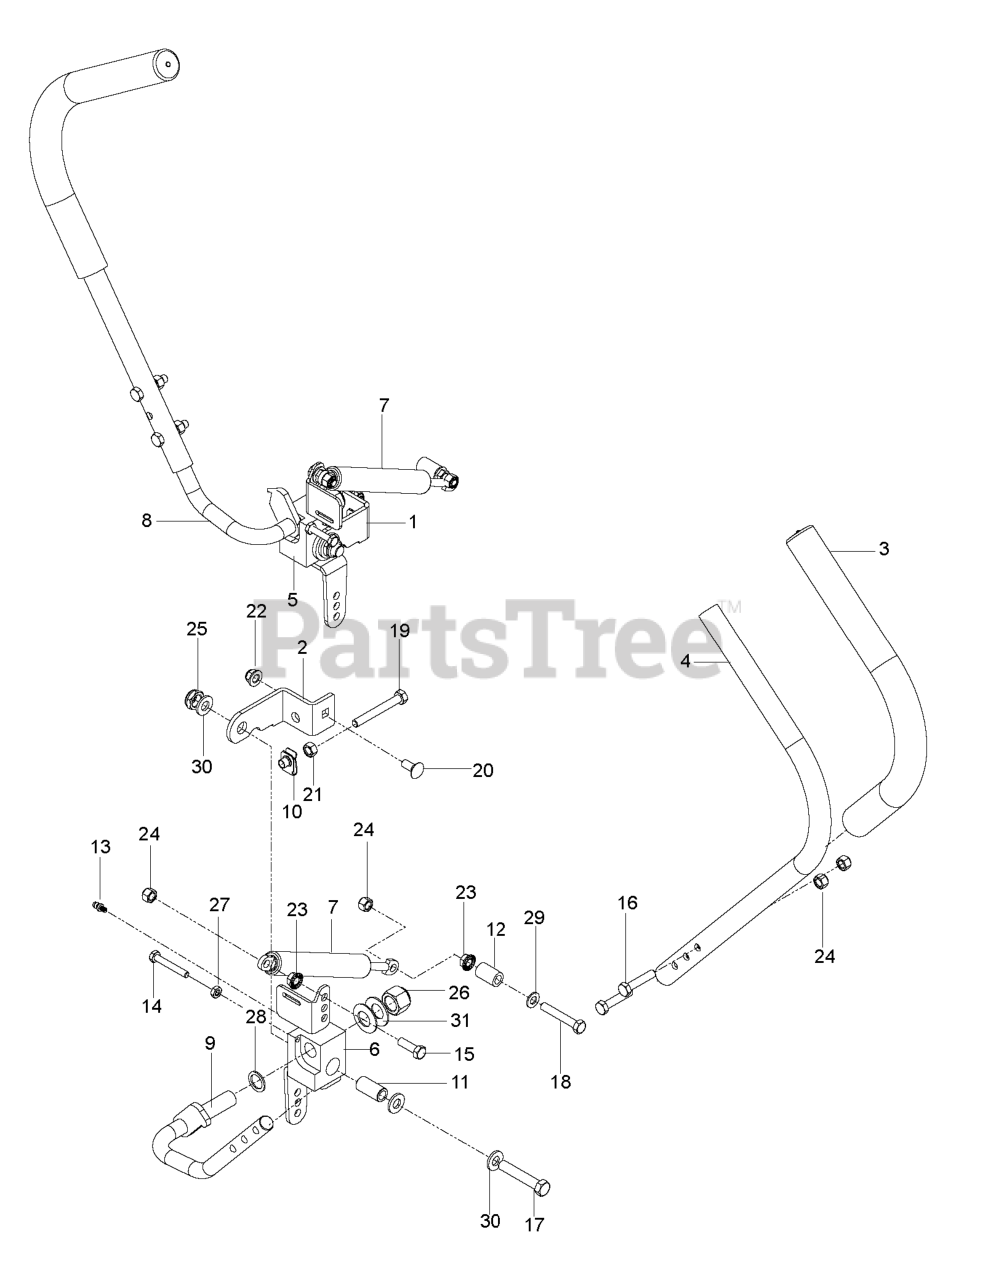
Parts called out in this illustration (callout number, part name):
1	FORWARD STOP RH
2	FORWARD STOP LH
4	LEVER UPPER
5	PIVOT RH (PLATED)
6	PIVOT LH (PLATED)
7	DAMPENER, DUAL ACTION
8	LEVER.PLATED.RH
9	LEVER PLATED LH
10	U-CLIP 5/16-18 NUT RETAINER
13	ZERK, 3/16, DRIVE IN
14	HCS.1/4-20 X 1-3/4 GR 5 ZD
15	BOLT.FIN.HEX.5/16-18UNC X 1.00
16	HEX BOLT
17	HCS 1/2-13 X 2-3/4 GD 5 ZD
18	HCS 5/16-18X2
19	HCS 5/16-18 X 2-1/2 GR 5 ZD
20	RP BOLT 5/16-18 X3/4 ZN/YEL GR
22	5/16-18 NYLOC FLANGE NUT
23	NUT LOCK HEX FLANGE 5/16-18
24	NUT.71038.31-18.HEX.NYLOCK
25	NUT 1/2-13 HEX JM NYL
26	NUT 5/8-11 NYLOC
27	NUT 1/4-20 JAM
28	WASHER-.626IDX.056TK
29	WASHER
30	WASHER STEEL
31	WASH 5/8 BEVELED DISC SPRING
